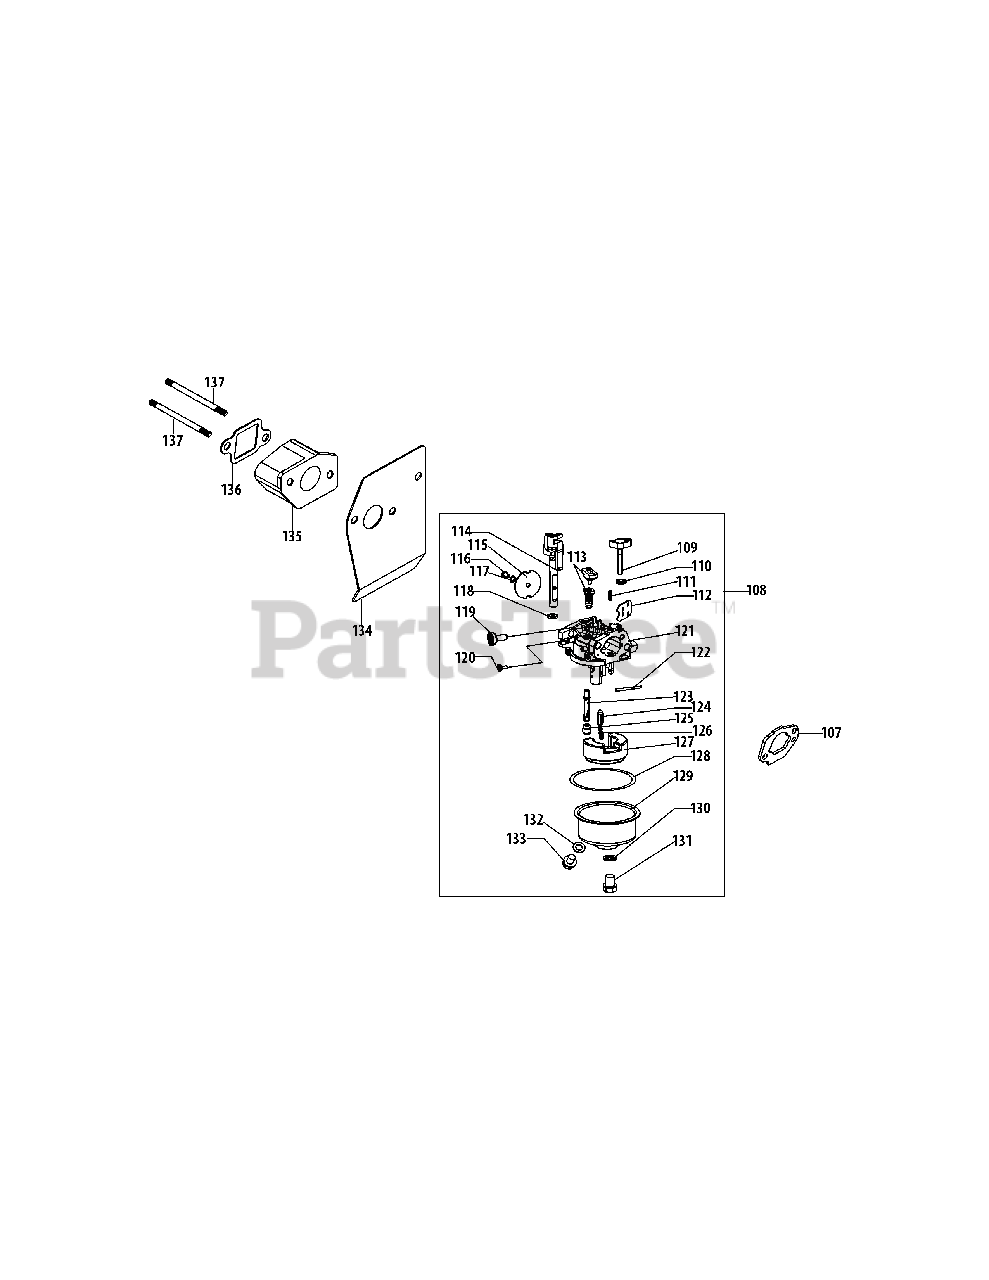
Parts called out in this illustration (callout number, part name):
107	Carburetor Gasket Plate
108	Carburetor Assembly
109	Choke Shaft
110	Fiber O-Ring
111	Choke Detent Spring
112	Choke Plate
113	Idle Jet Assembly
114	Throttle Shaft
115	Throttle Plate
116	Screw M3X6 Throttle Plate
117	Lock Washer
118	Fiber O-Ring
119	Idle Speed Adjusting Screw
120	Idle Mixture Screw
121	Carburetor Body
122	Float Pin
123	Emulsion Tube
124	Needle Valve
125	Main Jet
126	Needle Valve Spring
127	Float
128	Fuel Bowl O-Ring
129	Fuel Bowl
130	Fuel Bowl Gasket
131	Fuel Bowl Mounting Bolt
132	Fuel Drain Plug Gasket
133	Fuel Drain Plug
134	Carburetor Gasket
135	Carburetor Insulator
136	Carburetor Insulator Gasket
137	Carb Stud M6X113
